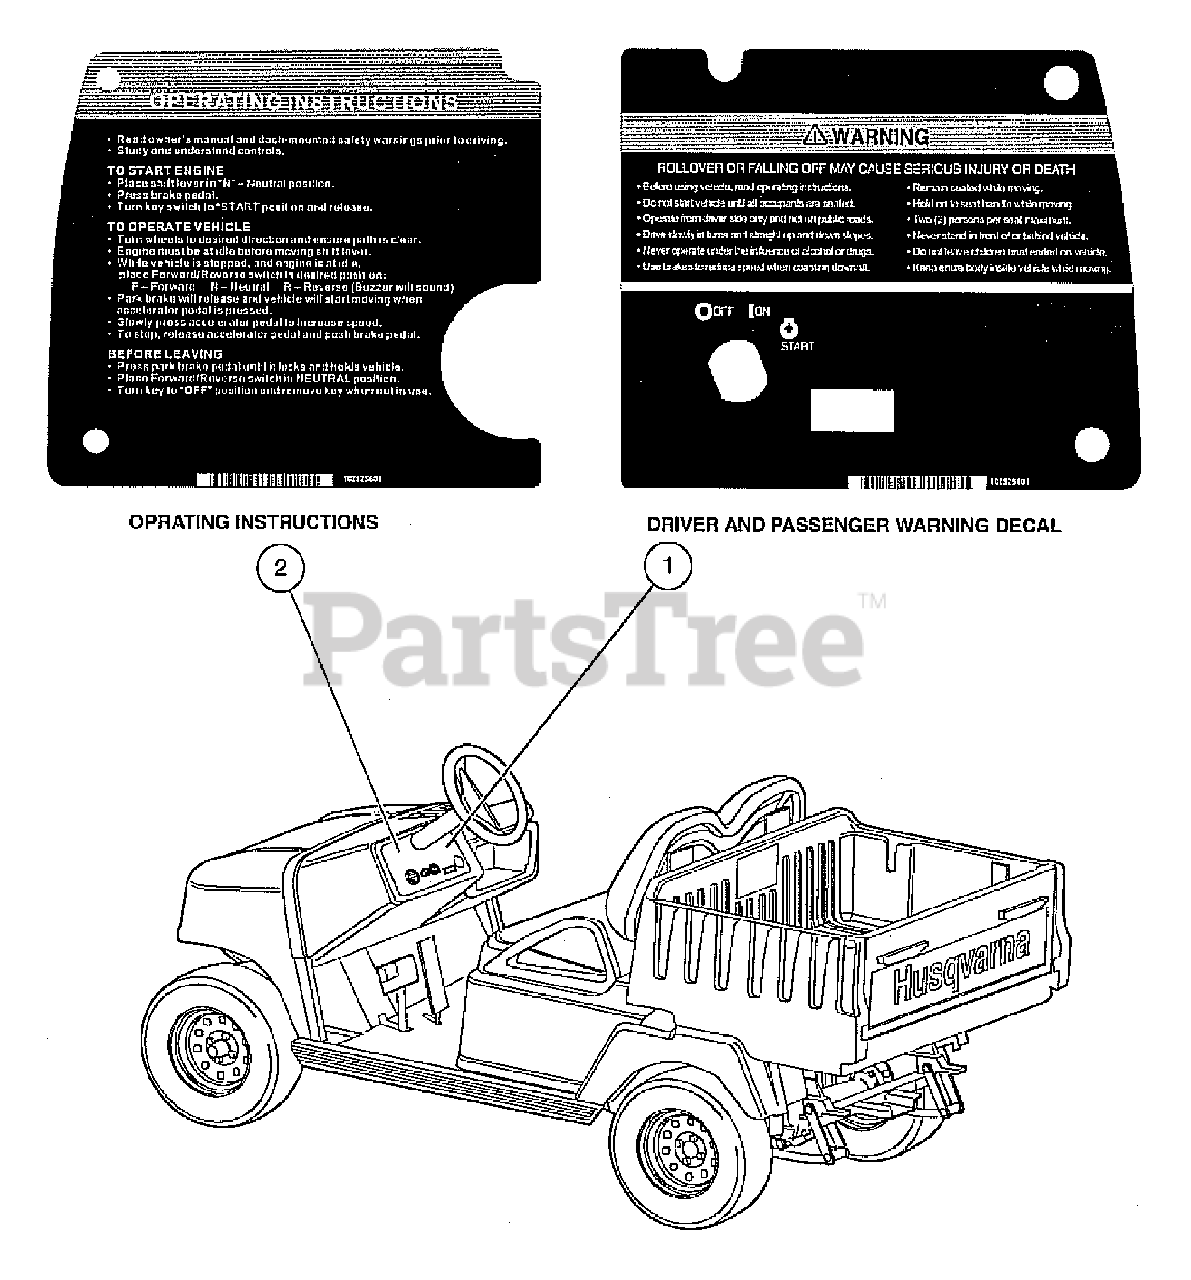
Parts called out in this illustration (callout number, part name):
1	Decal, Warning, Instrument Panel
2	Decal, Warning, Instrument Panel
3	Decal, Operating Instructions, Instrument Panel
